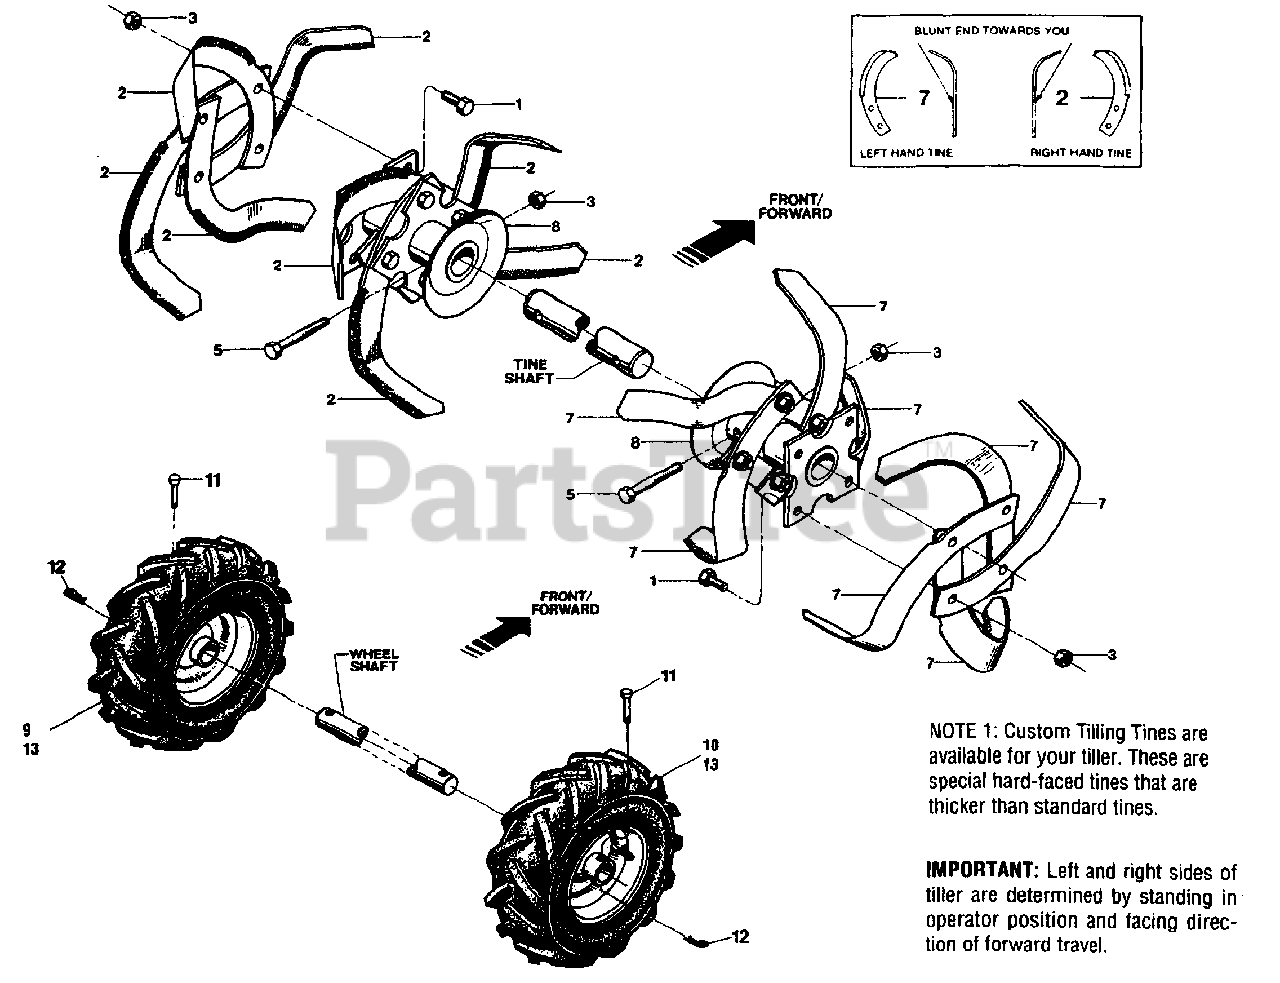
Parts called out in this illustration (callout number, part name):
1	Hex Hd. Screw, 3/8-16 x 1-1/4
2	Bolo Tine-single.
3	Hex Locknut, 3/8-16
5	Hex Hd. Screw, 3/8-16 x 2, Grade 8
7	Bolo Tine-single.
8	Tine Holder.
9	Wheel and Tire Assy., left side, 4.10 x 6 tire on 6" wheel
10	Wheel & Tire Assy., right side, 4.10 x 6 tire on 6" wheel
11	Clevis Pin, .312 x 1-3/4
12	Hitch Pin
13	Wheel and Tire Assembly
